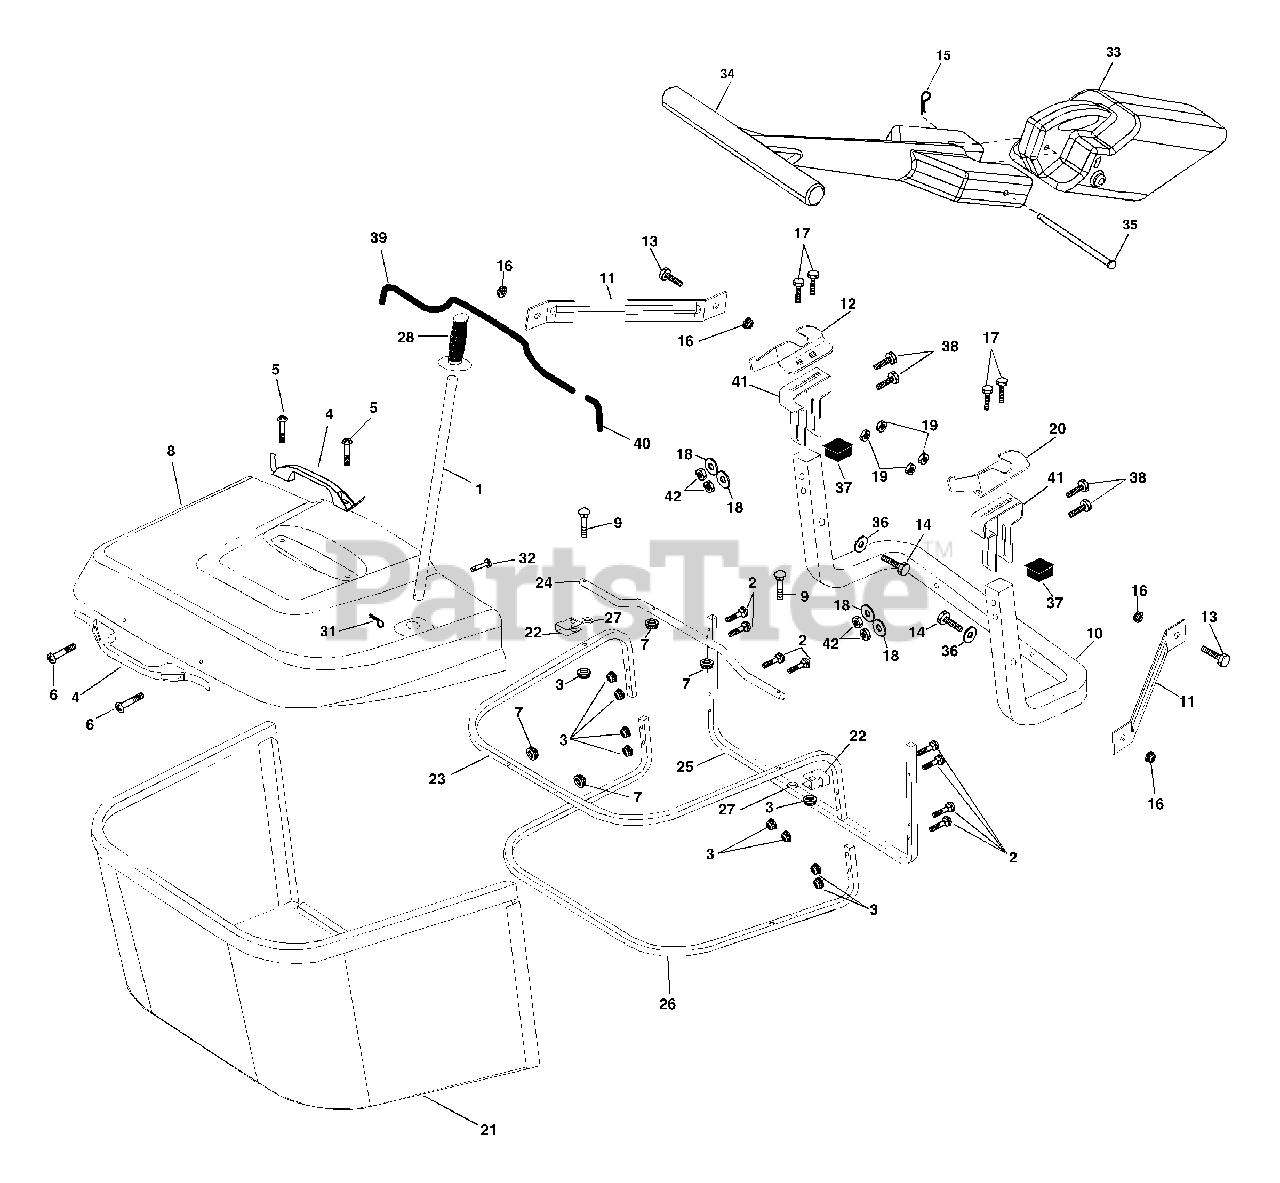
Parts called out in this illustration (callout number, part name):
1	Tube Handle Bagger CRD
2	Bolt Carriage 1/4-20 x 2.0 Gr.5
3	Nut Lock 1/4 Lge Flg Gr. 5 Zinc
4	Handle Bagger w/Lvrs Blk CRD
5	Screw Pan Head #10-24 x 1.50 Blk
6	Screw Pan Hd
7	Nut Wiz Lock Hex Serr/Hd 10-24
8	Cover Bagger Plastic CRD MS422
9	Bolt Carriage 1/4-20 x 2.25d x Gr.5
10	Tube Support Bagger CRD
11	Bracket Support Upper Bag CRD
12	Bracket Horiz Adj Bagger Lh CRD
13	Bolt Rdhd Sht Sqnk 3/8-16 x 3/4
14	Bolt Hex 3/8-16 x 2-1/2 Gr.5
15	Retainer Spring
16	Nut Lock Flg 3/8-16 Unc
17	Bolt Rdhd Sht Sqnk 5/16 -18 Unc x 3/4
18	Washer 11/32 x 3/4 x 16 Ga
19	Nut Lock Hexflange 5/16-18
20	Bracket Horiz Adj Bagger Rh CRD
21	Bag Asm CRD
22	Bracket Side Bagger CRD
23	Tube Upper Bagger CRD
24	Tube Pivot Bagger CRD
25	Tube Front Bagger CRD
26	Tube Lower Bagger CRD
27	Bushing Snap Bagger CRD
28	Grip Handle Black
31	Retainer Spring 1" Zinc/Cad
32	Rivet Rd Hd Drilled 3/8 Dia
33	Plug Mulcher 92 CRD
34	Handle Mulcher 92/107 CRD
35	Pin Mulcher 92/107 CRD
36	Washer 13/32 x 1-1/4 x 16 Ga.
37	Plug Support Bagger CRD
38	Bolt 5/16-18 x 2-1/2
39	Seal 26" (Long)
40	Seal 7" (Short)
41	Bracket Vert Adj Bagger CRD
42	Nut Lock Hex W/Ins 5/16-18 Unc Pl
